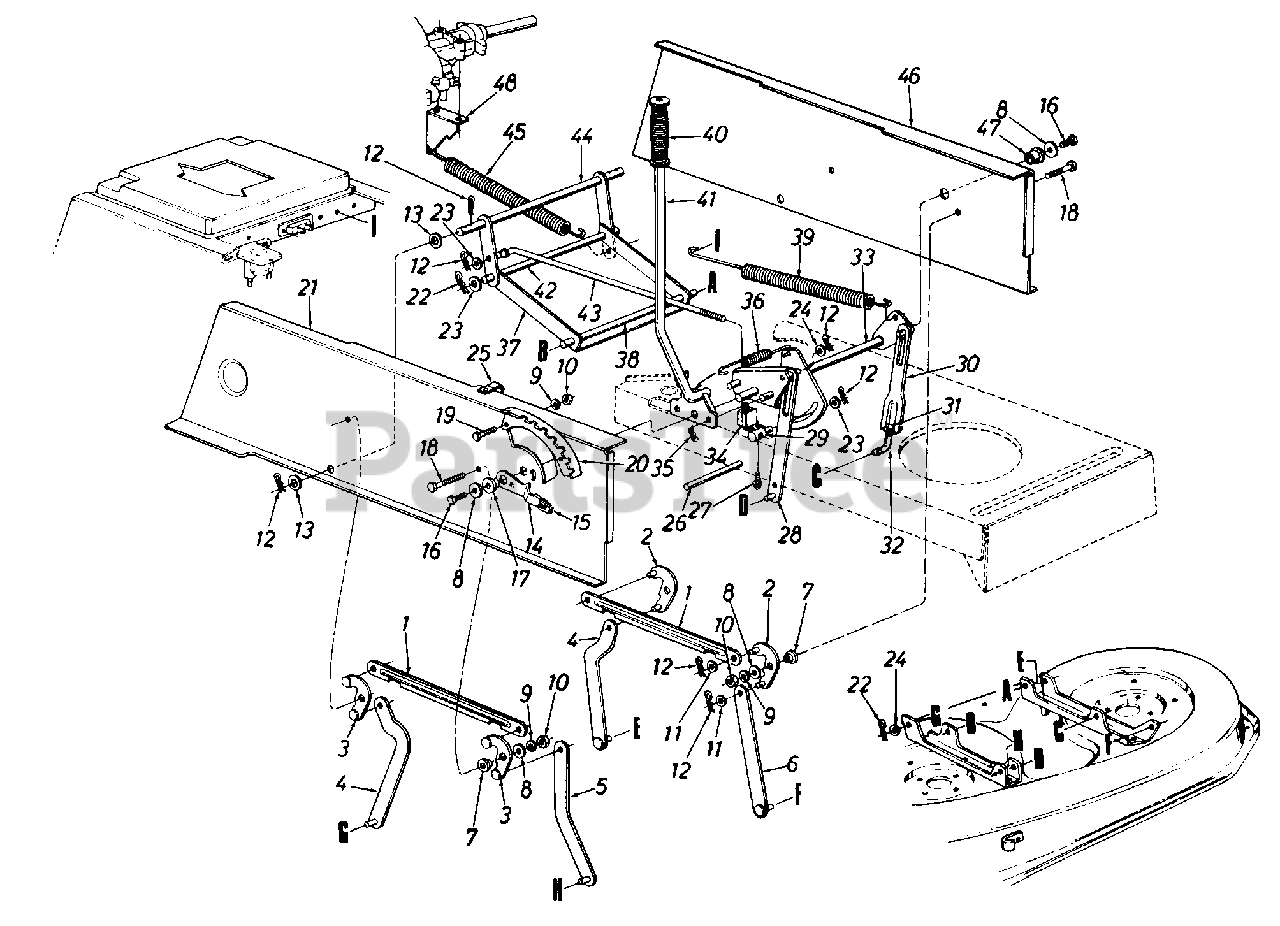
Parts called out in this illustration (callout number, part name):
1	Connecting Rod
2	Pivot Link Ass'y.-L.H.
3	Pivot Link Ass'y.-R.H.
6	Deck Hanger Link Ass'y.
7	Shld. Spacer .318" I.D.
8	Fl-Wash. .344" I.D. x 1.125"
9	L-Wash. 5/16" I.D.
10	Hex Nut 5/16-18 Thd.
11	Fl-Wash. .531" I.D. x .94" O.D.
12	Cotter Pin 1/8" Dia.
13	Fl-Wash. .635" I.D. x 1.0" O.D.
14	Deck Lift-Down Stop
16	Hex Wash. TT-Tap Scr. 5/16-18 x 75" Lg.
17	Flange Brg. .63" I.D.
18	Hex Wash. TT-Tap Scr. 5/16-18 x.875" Lg.
19	Hex Bolt 5/16-18 x .75" Lg.
20	Index Brkt.
21	Upper Frame-R.H.
22	Inter. Cotter Pin 1/2" Dia.
23	Fl-Wash. .385" I.D. x .87" O.D.
24	Fl-Wash. .531" I.D. x .93" O.D.
26	Running Board Rod
27	Truss Mach. Scr. #10 x .5" Lg.
31	Hex Jam Nut 1/2-20 Thd. (Gr. 5)
32	Lift Link Adjuster
33	Lift Shaft Ass'y.
34	Safety Switch
35	Inter. Cotter Pin 318" Dia.
36	Extension Spring
37	Stabilizer Bracket
38	Shaft 1/2" Dia. x 10.28" Lg.
39	Extension Spring
40	Grip
41	Deck Lift Handle Ass'y.
42	Shaft 318" Dia. x 9.34" Lg.
43	Disengagement Rod
44	Stabilizer Shaft Ass'y.
45	Extension Spring
46	Upper Frame-L.H.
47	Flange Brg. .632" I.D.
48	Spring Retainer Brkt.
